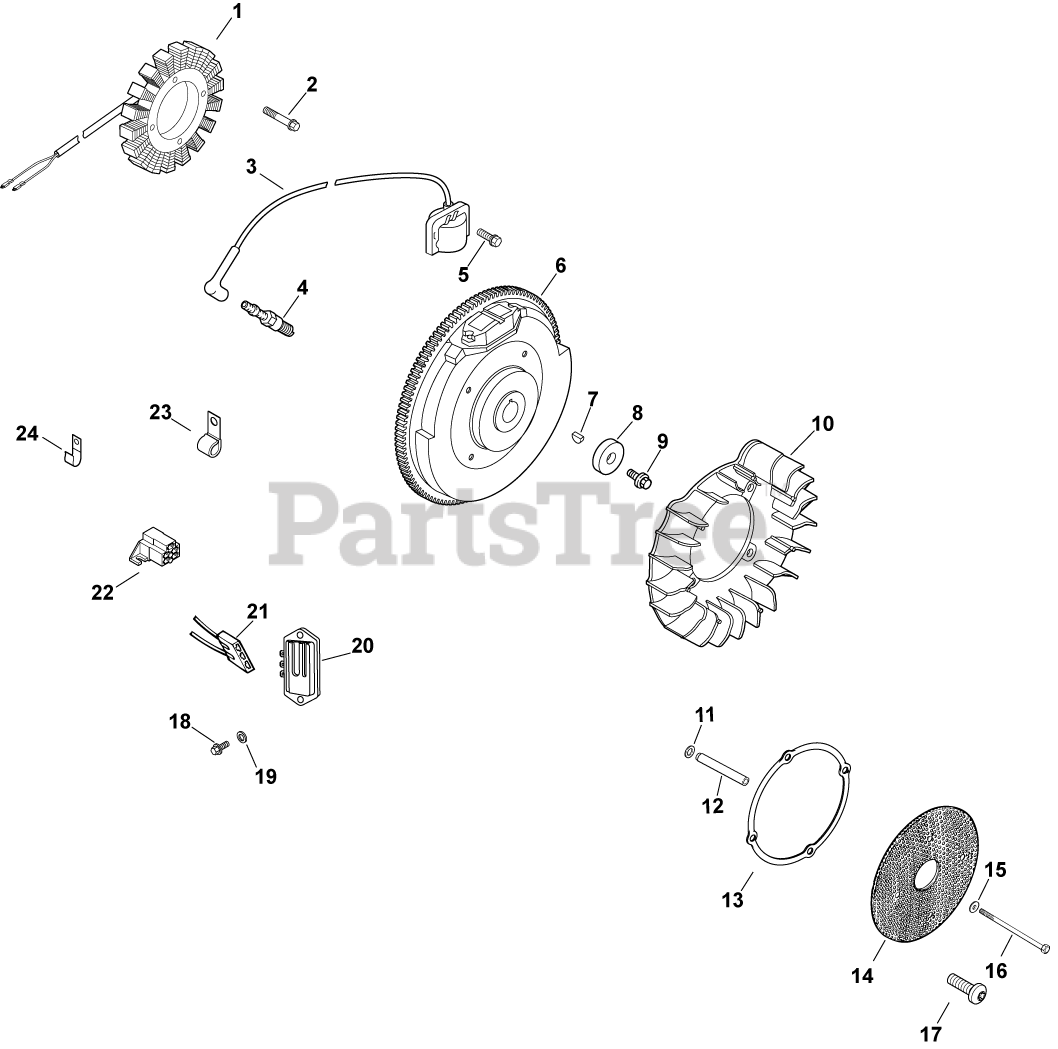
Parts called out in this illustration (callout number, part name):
1	KIT, 15 / 20 AMP STATOR
2	SCREW, M5X0.8X25 - (#25086402S)
3	KIT, MODULE IGNTN (CDI FIXED)
4	PLUG, SPARK (STD)
5	SCREW, FLG THD FRM M5X.8X20-(#25086399S)
6	FLYWHEEL, PAINTED-USE 24 025 55-S
7	KEY, 3/16" X 5/8"
8	WASHER, FLAT 13/32"
9	SCREW, FLG M10X1.5X45 - (#25086361S)
10	FAN USE 24 755 253-S
11	WASHER, SPRING 10 MM
13	RING, SUPPORT USE 25 141 08-S
14	SCREEN, GRASS-USE 24 162 39-S
15	WASHER, FLAT 1/4" (O.D. 5/8")
16	SCREW, CAP M6X1.0X99.5
17	SCREW, SKT SET #10-24X1/4"
18	SCREW, PHL HD #11-16X7/8"
19	WASHER, FLAT 1/4" (O.D. 1/2")
20	CONNECTOR, BODY (KM)-USE 25 155 41-S
21	REG/RECT-15 AMP (KM)-USE 41 403 10-S
22	CONNECTOR
23	CLIP, TUBE & WIRING (KM)
24	CLIP, CABLE
